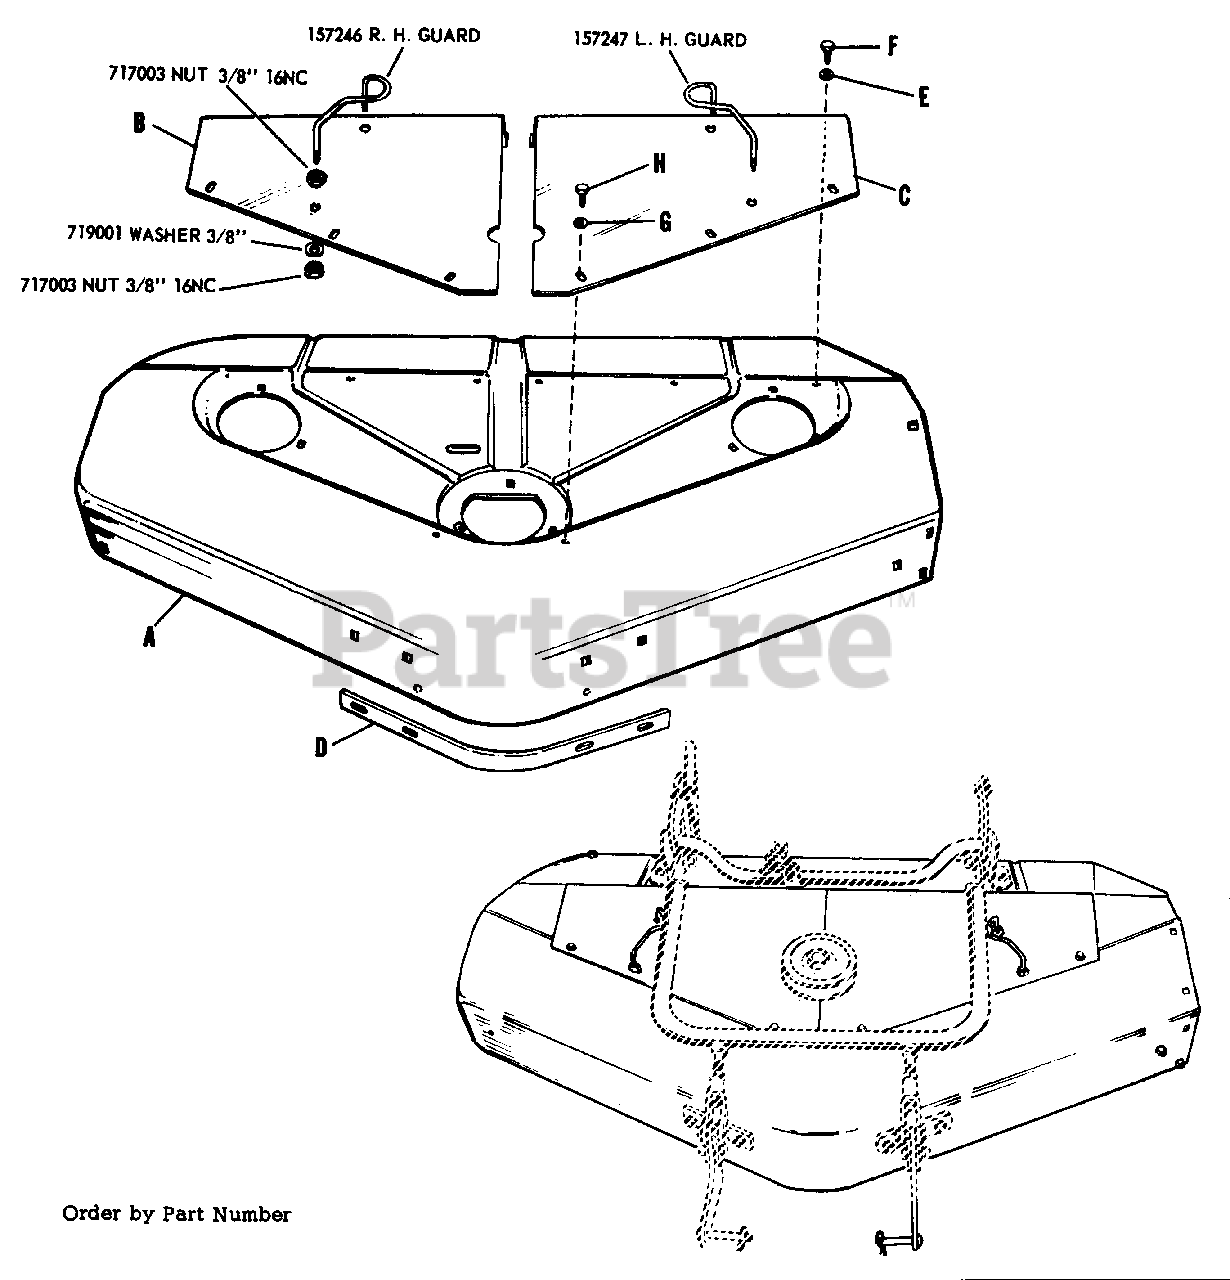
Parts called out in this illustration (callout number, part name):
A	Housing, Mower
B	Cover, R.H.
C	Cover, L.H.
D	Bar, Reinforcing
E	Washer, Plain, 3/16
F	Screw, Recessed Hex, Self-Tapping, 1/4-20 x 3/8"
G	Washer, Plain, 3/16"
H	Screw, Recessed Hex, Self-Tapping, 1/4-20 x 3/8"
